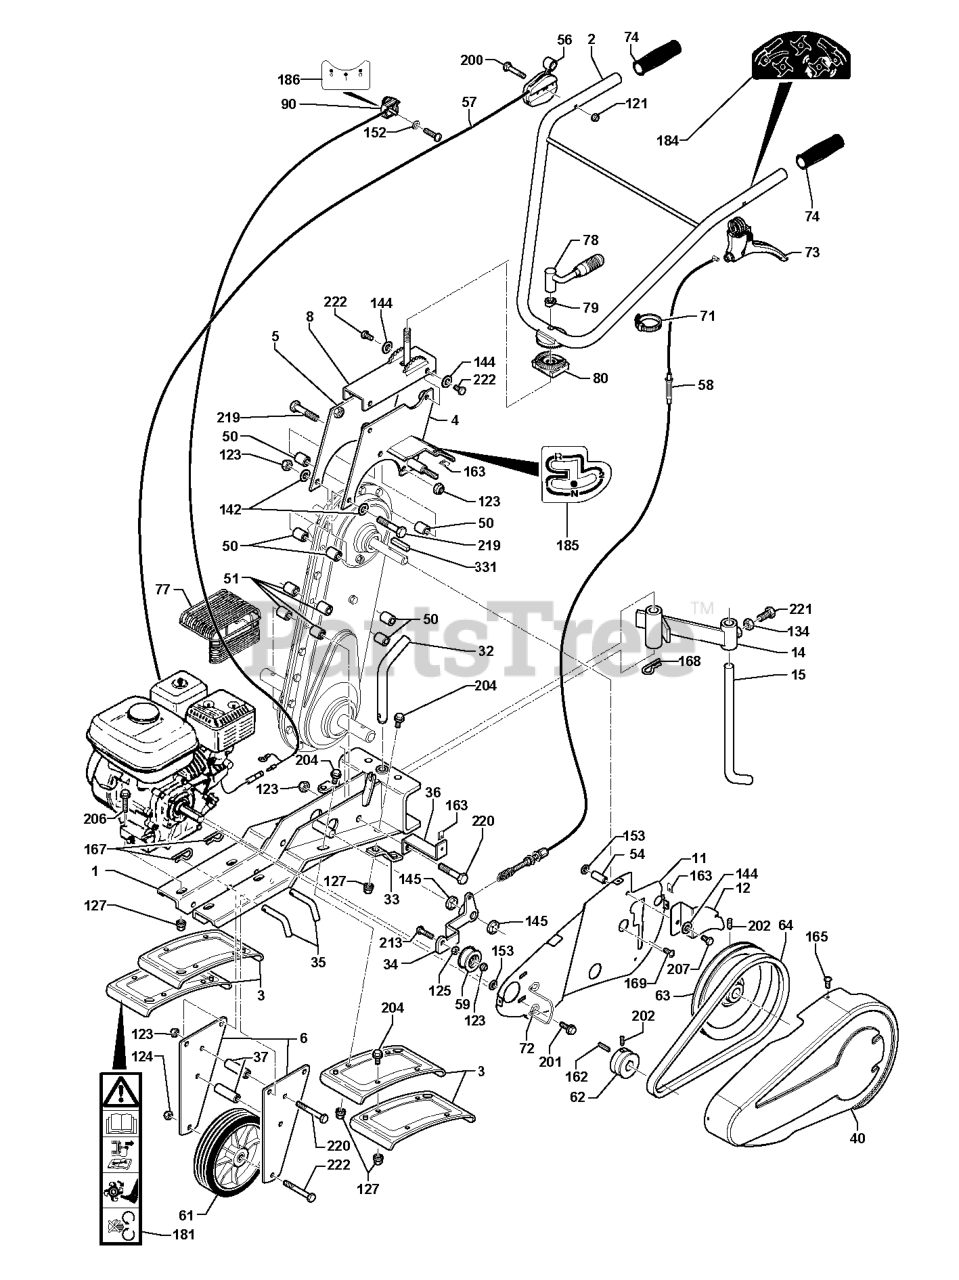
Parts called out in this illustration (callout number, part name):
121	Blocking nut M 6 Z
142	WASHER
167	COTTER PIN
